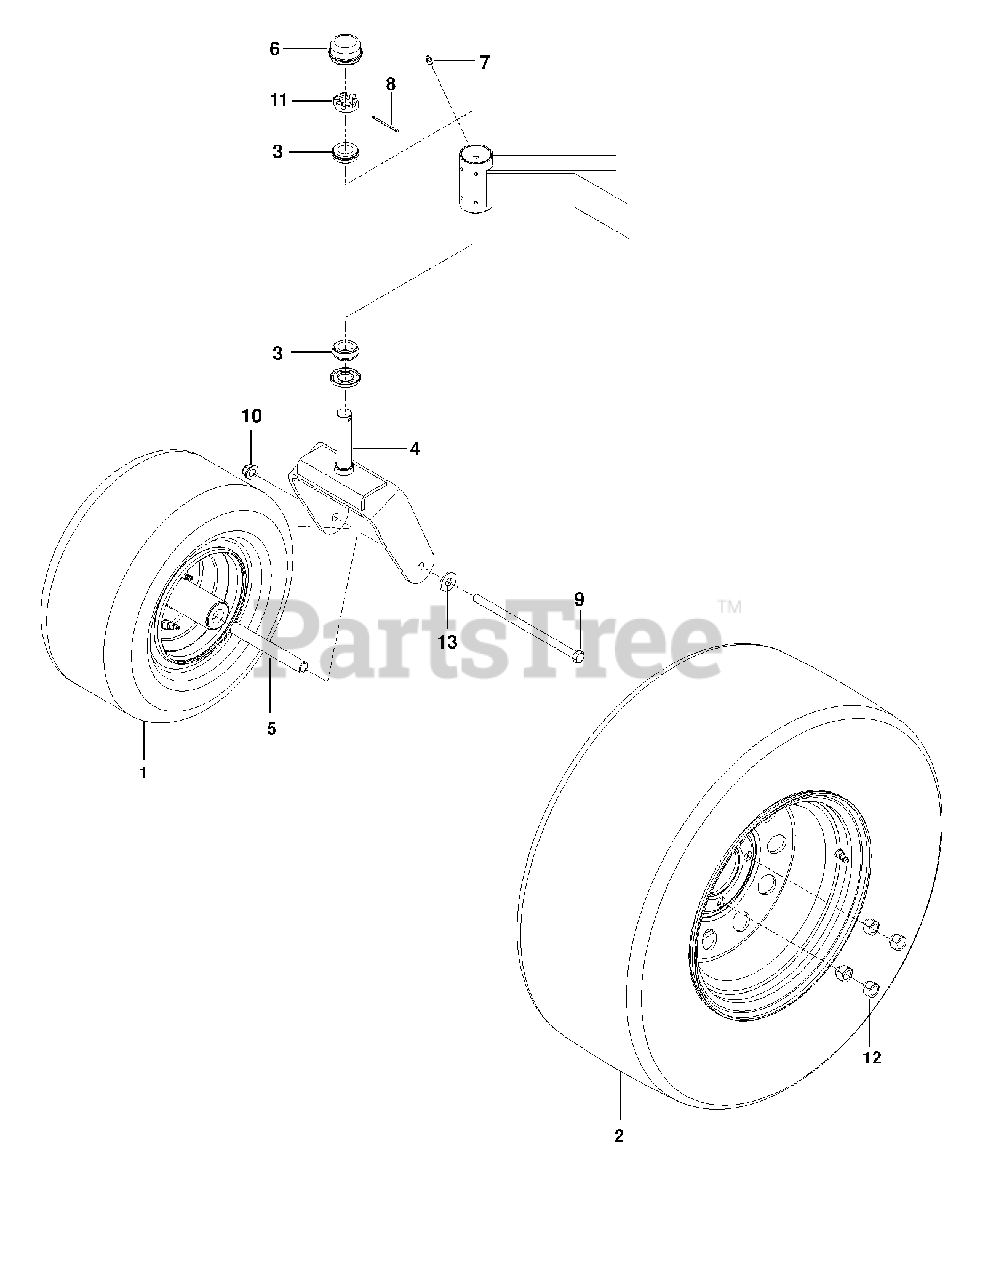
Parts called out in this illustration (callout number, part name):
2	ASSEMBLY, TIRE 23 X 9.20-12
3	TAPERED ROLLER BRG
4	YOKE, CASTER, BLUE
5	SPACER, PIVOT
6	GREASE CAP
9	HEX SCREW 1/2-13 X 9.5 GR5
10	NUT, 1/2-13 HEX FLG NYLOC ZD
11	NUT 1"C HEX SLOTTED
12	LUG NUT 1/2F
13	WASH USS FLAT 1/2
